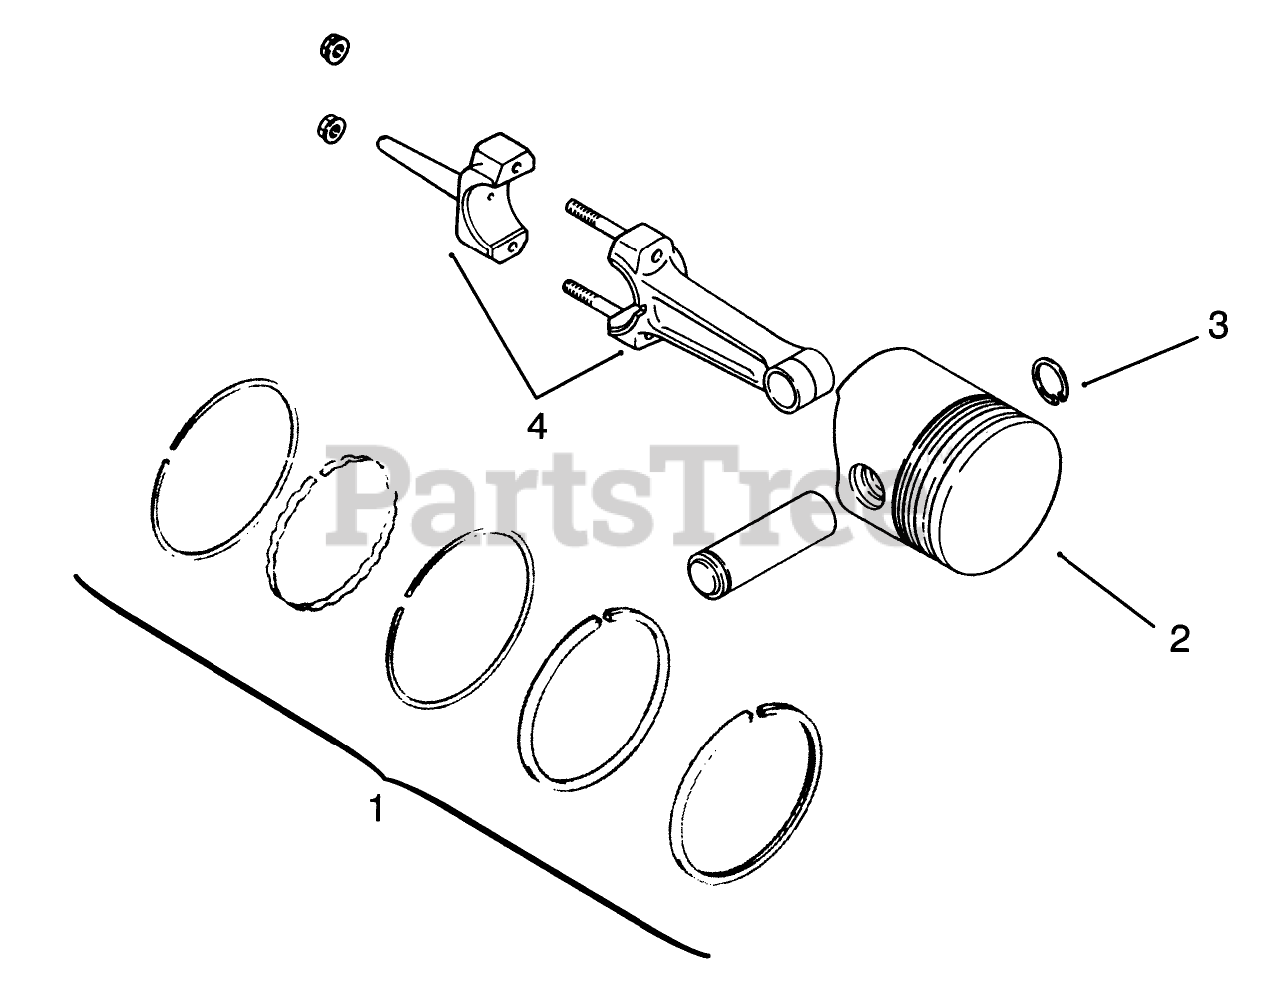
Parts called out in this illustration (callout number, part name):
1	VNDR #47-108-05
2	VNDR #47-874-21
3	KOHLER 47-018-01
4	VNDR #45-067-24
